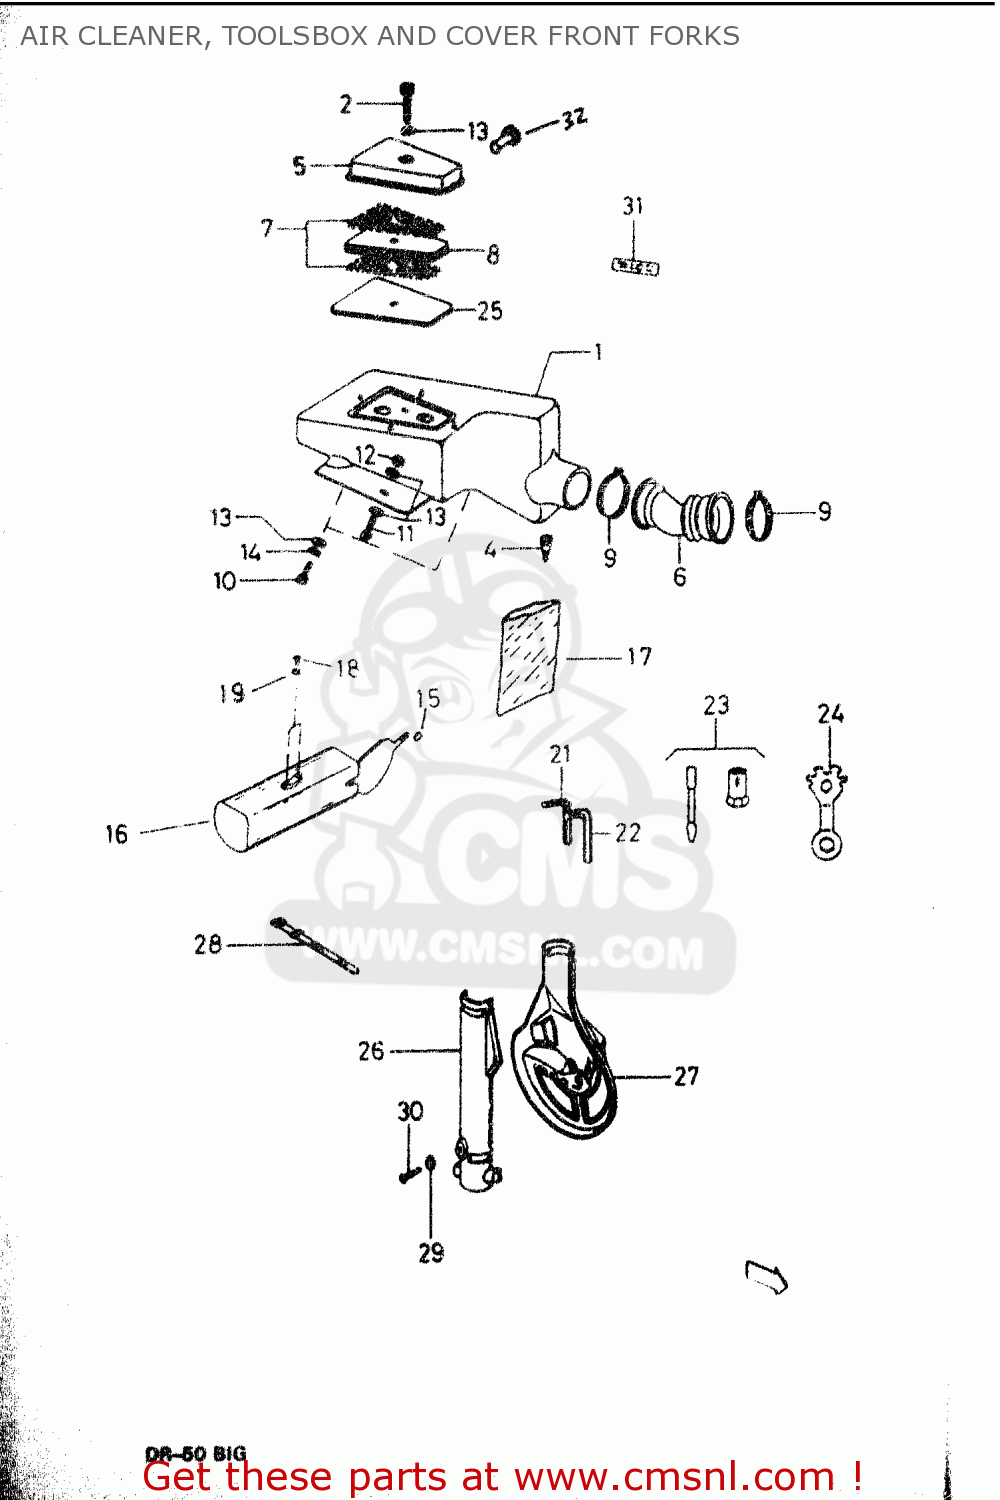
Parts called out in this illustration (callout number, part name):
1	CLEANER ASSY, AIR
2	SCREW
4	TUBE, DRAIN
5	CAP
6	TUBE, OUTLET
7	HOLDER
8	FILTER
9	CLAMP 50-70
10	SCREW M6X10 DIN 7985/N
11	SCREW M6X16 DIN 7985/N
12	NUT M6 DIN 985
13	WASHER 6 DIN 9021
14	WASHER A6 DIN 137
15	RING
16	TOOL CASE
17	TOOL-POCKET
18	SCREW M5X15 DIN 7985
19	WASHER 5 DIN 6798
21	L TYPE HEXAGON WRENCH 4
22	L TYPE HEXAGON WRENCH 5
23	TOOLS SET
24	UNIVERSAL, WRENCH
25	FILTER N2
26	COVER FRONT FORKS, R (BLUE)
27	COVER FRONT FORKS, L (BLUE)
28	CLAMP
29	WASHER B6 DIN 9021/N
30	SCREW 6X12
31	EMBLEM FILTER
32	BUSH
